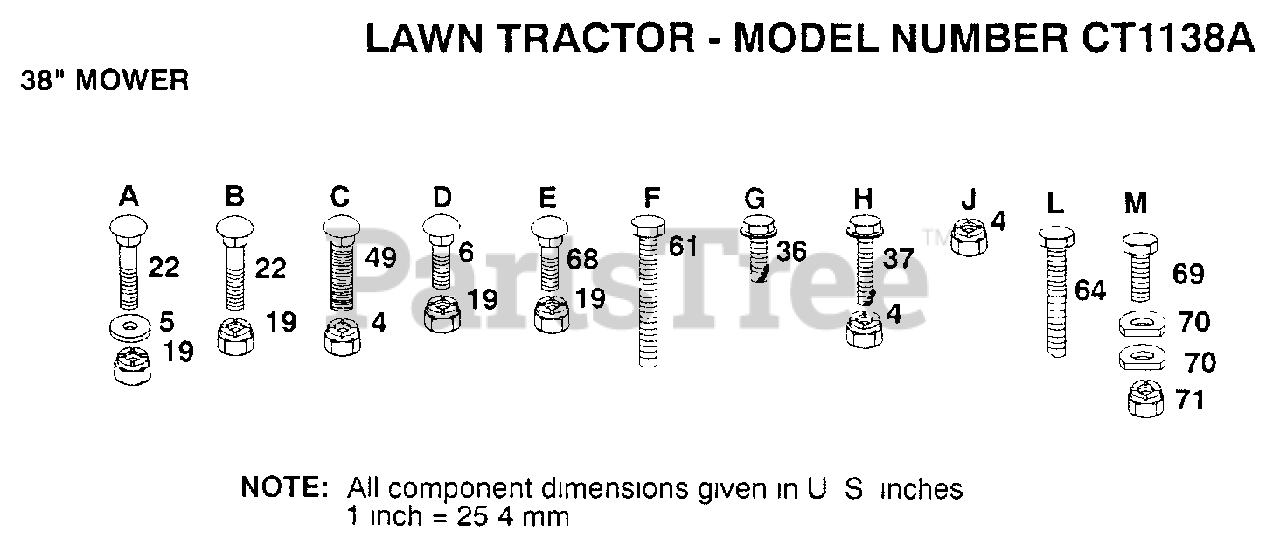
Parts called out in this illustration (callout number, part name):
5	WASHER M
6	BOLT
22	BOLT
36	SCREW
37	SCREW
49	BOLT
61	BOLT
64	BOLT.3/8-14X1.25
69	BOLT LT
70	WASHER T
